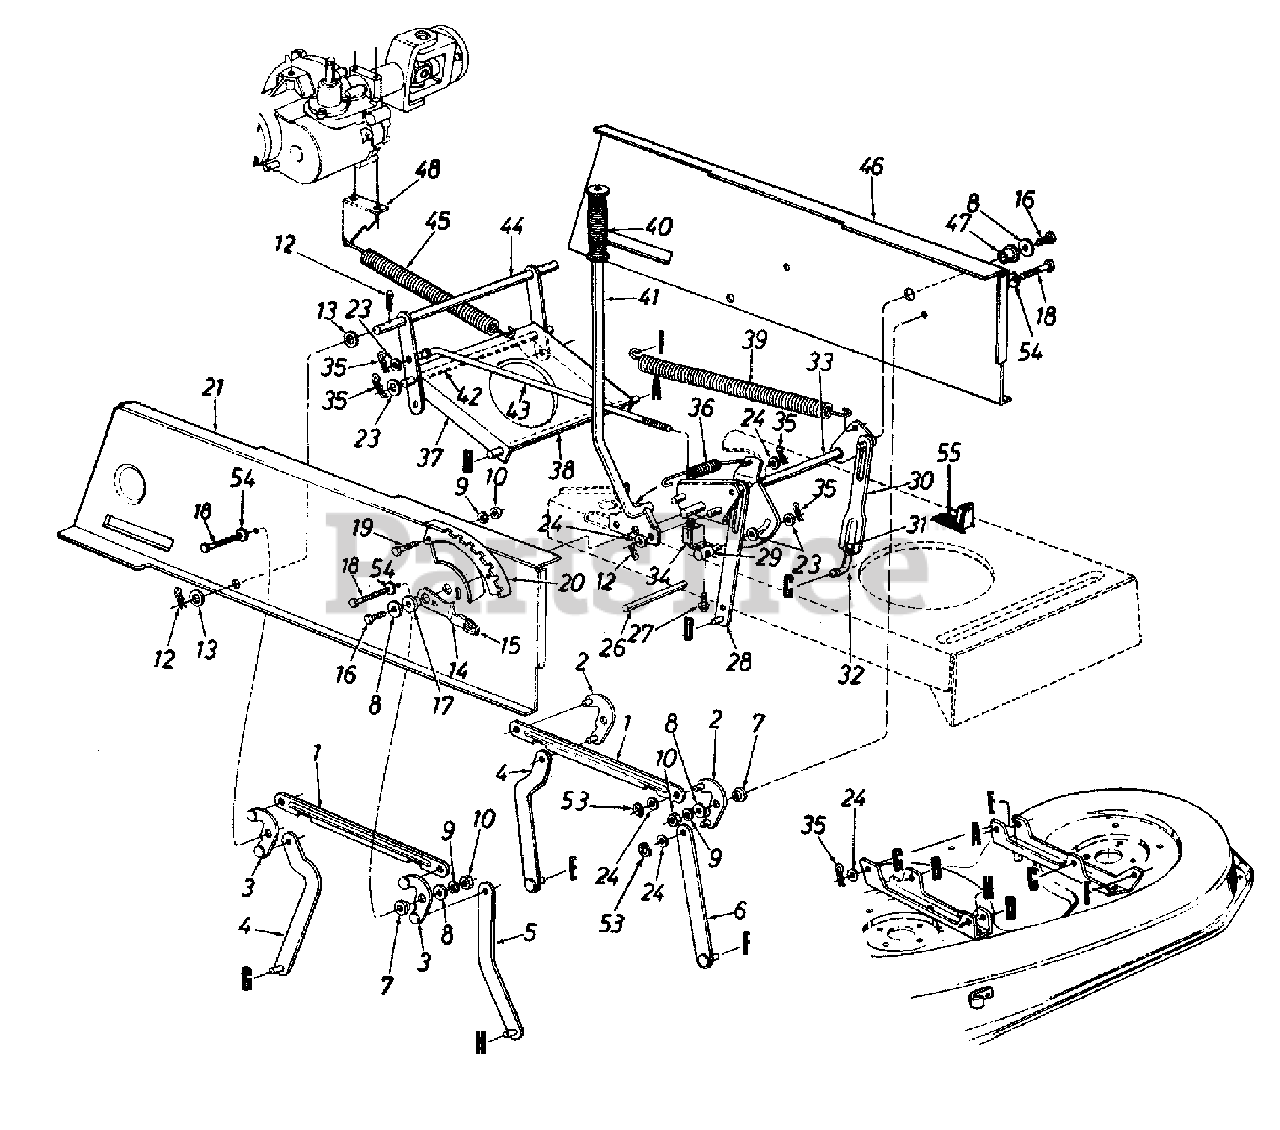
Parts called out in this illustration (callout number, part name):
3	Pivot Link Ass'y.-R.H.
7	Shld. Spacer .318" I.D.
8	Fl-Wash. .344" I.D. x 1.125"
9	L-Wash. 5/16" I.D.
10	Hex Nut 5/16-18 Thd.
12	Cotter Pin 1/8" Dia.
13	Fl-Wash. .635" I.D. x 1.0" O.D.
14	Height Adj. Stop Lever Ass'y.
15	Knob
16	Hex Wash. TT-Tap Scr.5/16-18 x .75" Lg.
17	Flange Brg. .63" I.D.
18	Hex Wash. Hd. Scr. 5/16-18x .875" Lg.
19	Hex Bolt 5/16-18 x .75" Lg.
20	Index Brkt.
21	Upper Frame-R.H.
23	Fl-Wash. .385" I.D. x .87" O.D.
24	Fl-Wash. .531" I.D. x .93" O.D.
26	Running Board Rod
27	Truss Mach. Scr. #10 x .5" Lg.
31	Hex Nut 1/2-20 Thd. (Gr. 5)
32	Lift Link Adjuster
33	Lift Shaft Ass'y.
34	Safety Switch (Deck)
35	Inter. Cotter Pin 3/8" Dia.
36	Extension Spring
39	Extension Spring
40	Grip (Lift Handle)
43	Disengagement Rod
46	Upper Frame-L.H.
47	Flange Brg. .632" I.D.
53	E-Ring
54	Bell-Wash. .325" I.D.
55	Spring Switch
